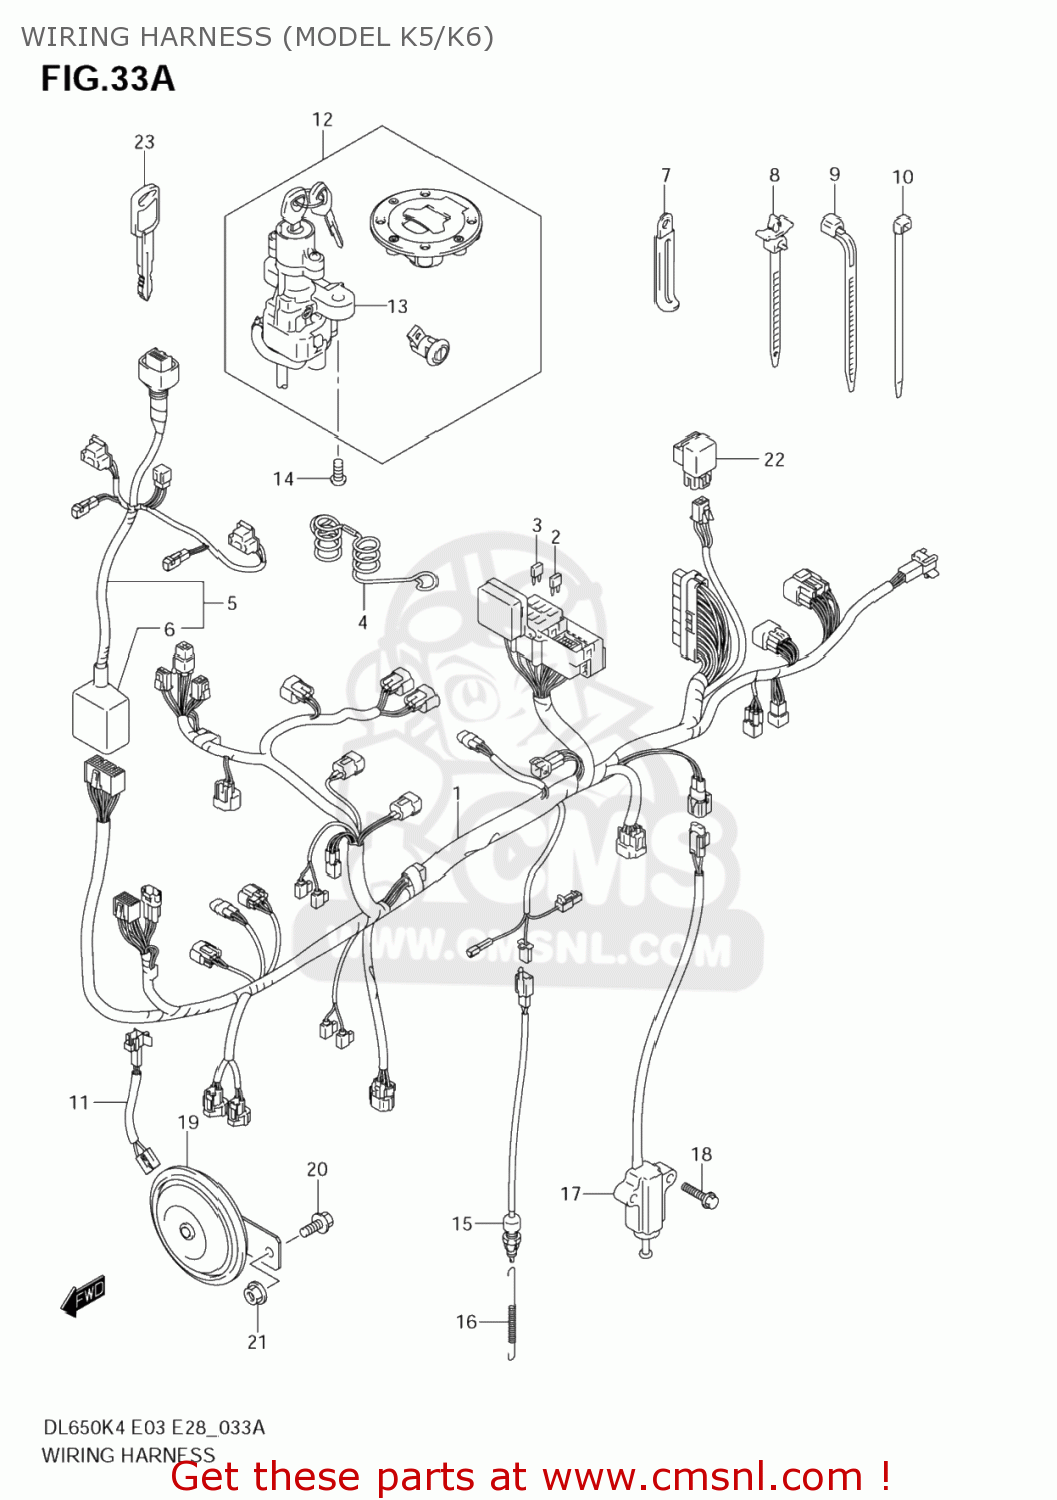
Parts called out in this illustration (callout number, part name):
1	HARNESS, WIRING, NO.1
2	FUSE(10A)
3	FUSE(15A)
4	GUIDE,WIRING HARNESS
5	HARNESS,WIRING NO.2
6	COVER,CONNECTOR
7	CLAMP(L:45)
8	CLAMP(L:90)
9	CLAMP(L:95)
10	CLAMP(L:145)
11	WIRE,HORN LEAD
12	LOCK SET
13	LOCK ASSY,STEERING
14	BOLT(8X20)
15	SWITCH ASSY,STOP LAMP
16	SPRING
17	SWITCH ASSY,SIDE STAND
18	BOLT
19	HORN ASSY
20	BOLT
21	NUT
22	RELAY ASSY
23	KEY,BLANK
